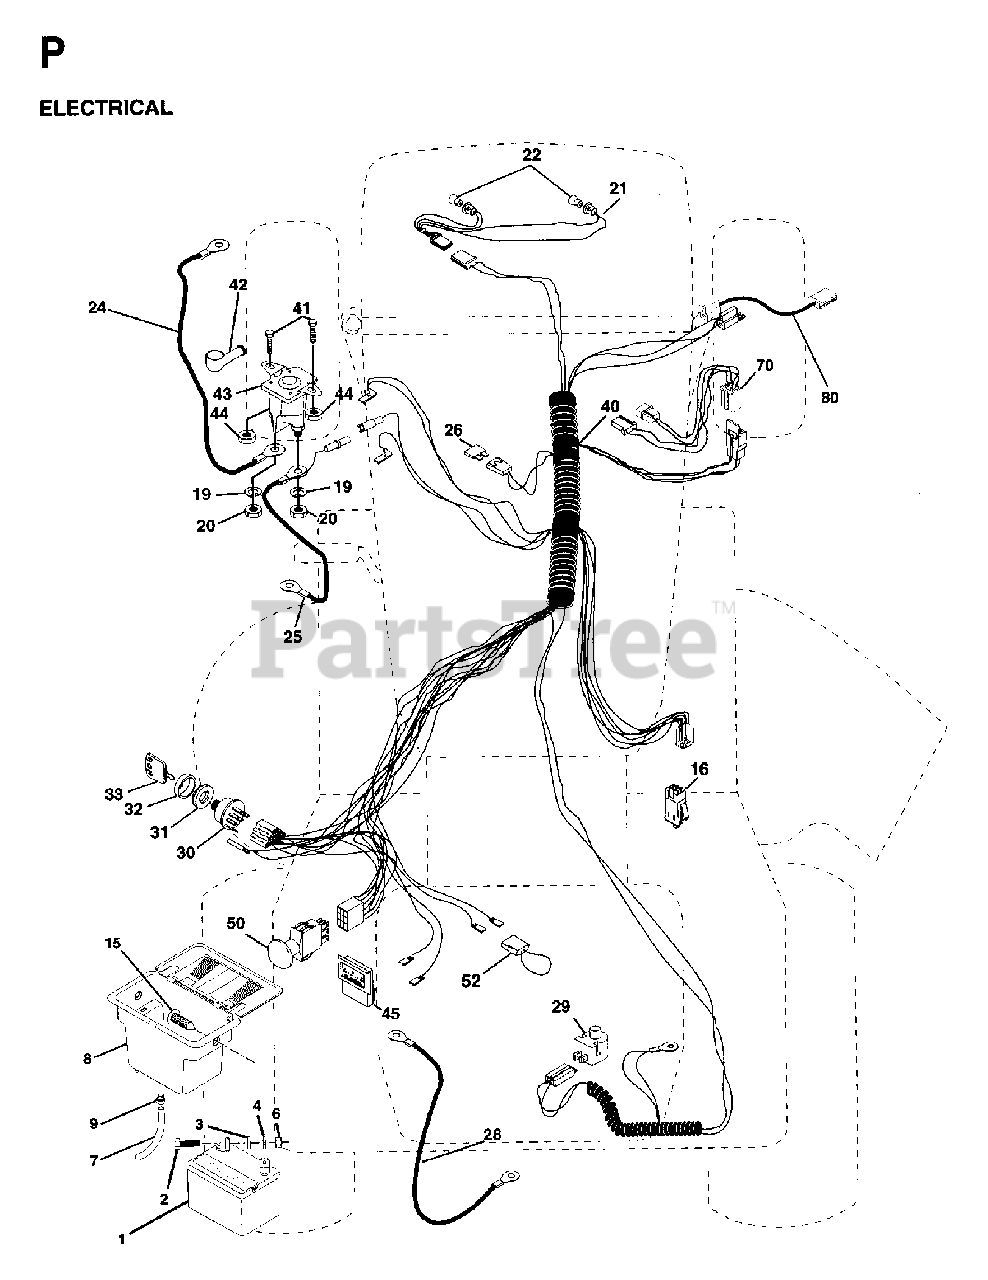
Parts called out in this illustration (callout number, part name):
1	BATTERY.DRY.30.AMP
3	WASHER
4	LOCKWASHER
6	NUT
7	TUBE BATTERY DRAIN
8	CASE BATTERY MECH HINGE
9	HOSE CLAMP T
16	SWITCH INTERLOCK
19	LOCKWASHER
20	NUT
21	HARNESS ASM HDLIG
22	LIGHTBULB
24	BATTERY CABLE GT
25	CABLE BATTERY
28	CABLE T
29	SWITCH SEAT
30	SWITCH.IGNITION.4.POSITION
31	NUT IGNITION
32	COVER SWITCH KEY
40	IGN HARNESS
42	TERMINAL COVER
43	SOLINOID
50	SWITCH PTO 3 PDT
52	WIRE PROTECTION LOOP
70	HARNESS ENGINE
80	HARNESS, CLUTCH
